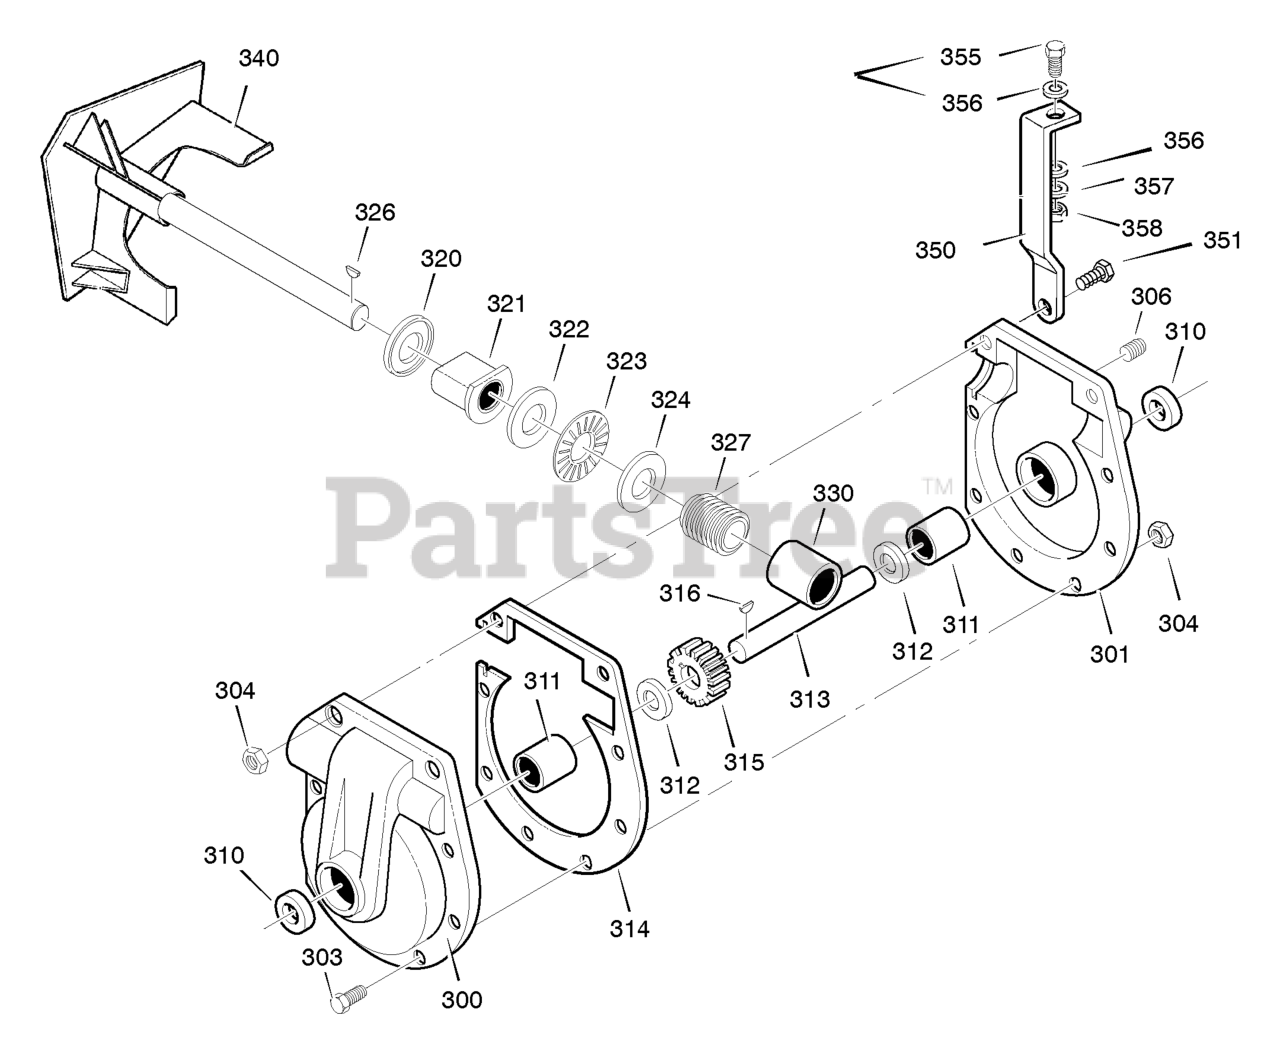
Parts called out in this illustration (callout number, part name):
300	CASE, GEAR, RH
301	CASE, GEAR, LH
303	SCREW, 5/16-24 x 1.00
304	NUT, 5/16-24
306	PLUG, PIPE 0.25-18
310	SEAL, OIL
311	BEARING, SLEEVE
312	WASHER, FLAT
313	SHAFT, AUGER OUTPUT
314	GASKET, GEAR BOX
315	WORM GEAR
316	KEY, WOODRUFF #91
320	RING, QUAD 0.924 ID
321	BEARING, FLANGE
322	WASHER, FLAT
323	BEARING, ROLLER
324	WASHER, FLAT
330	BEARING, SLEEVE
350	BRACE, GEAR BOX
351	SCREW, 5/16-24 x 1.75
355	SCREW, 5/16-18 x 1.25
356	WASHER, FLAT
357	WASHER, SPTLK
358	NUT, REGHEX 5/16-18
